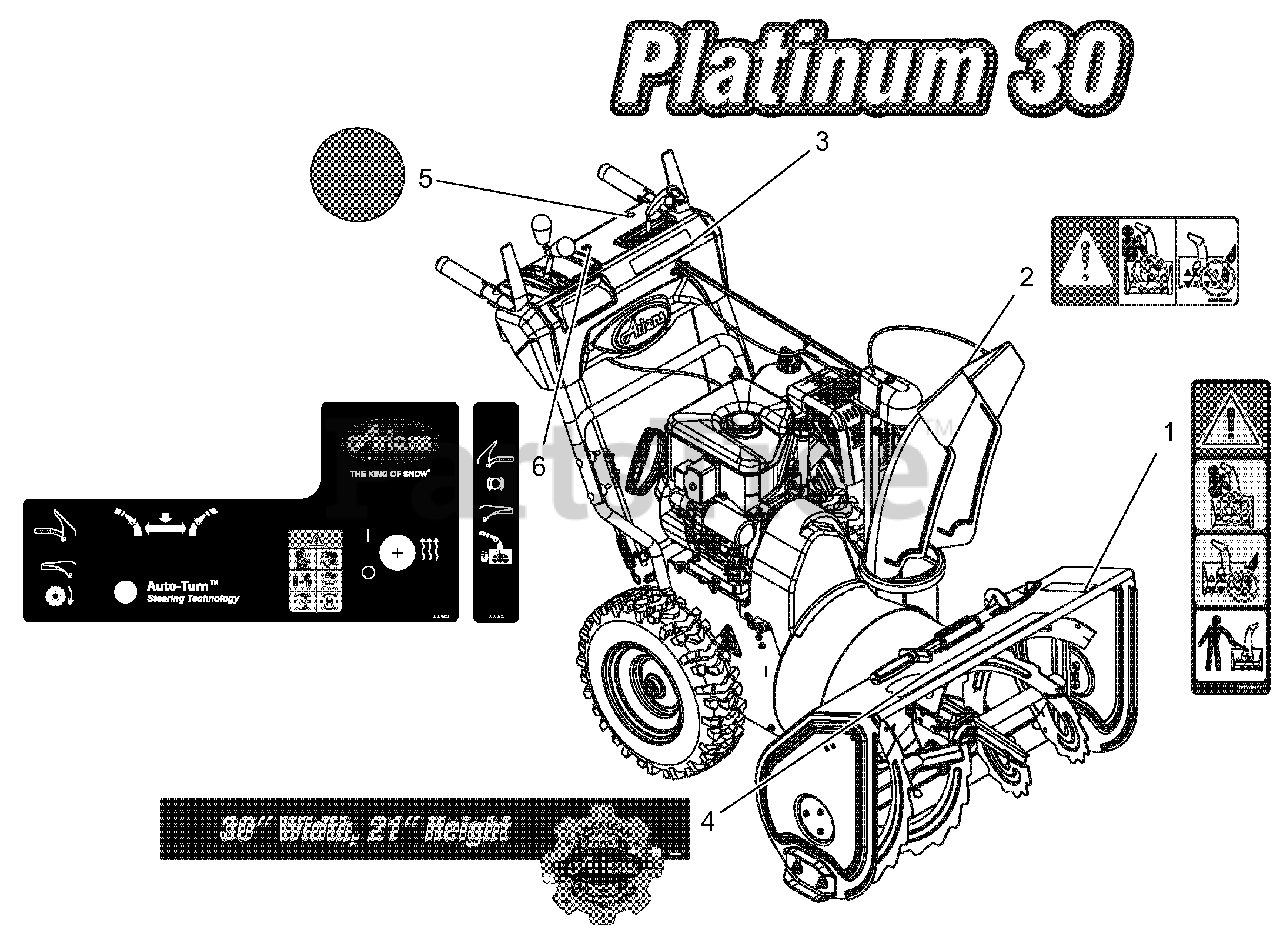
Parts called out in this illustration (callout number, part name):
1	DECAL, DANGER - ROTATING PARTS
2	DECAL, DANGER
3	DECAL, PLATINUM 30
5	DECAL,AUTODIFFERENTIAL
6	DECAL,CONTROL-LRG,QT2
